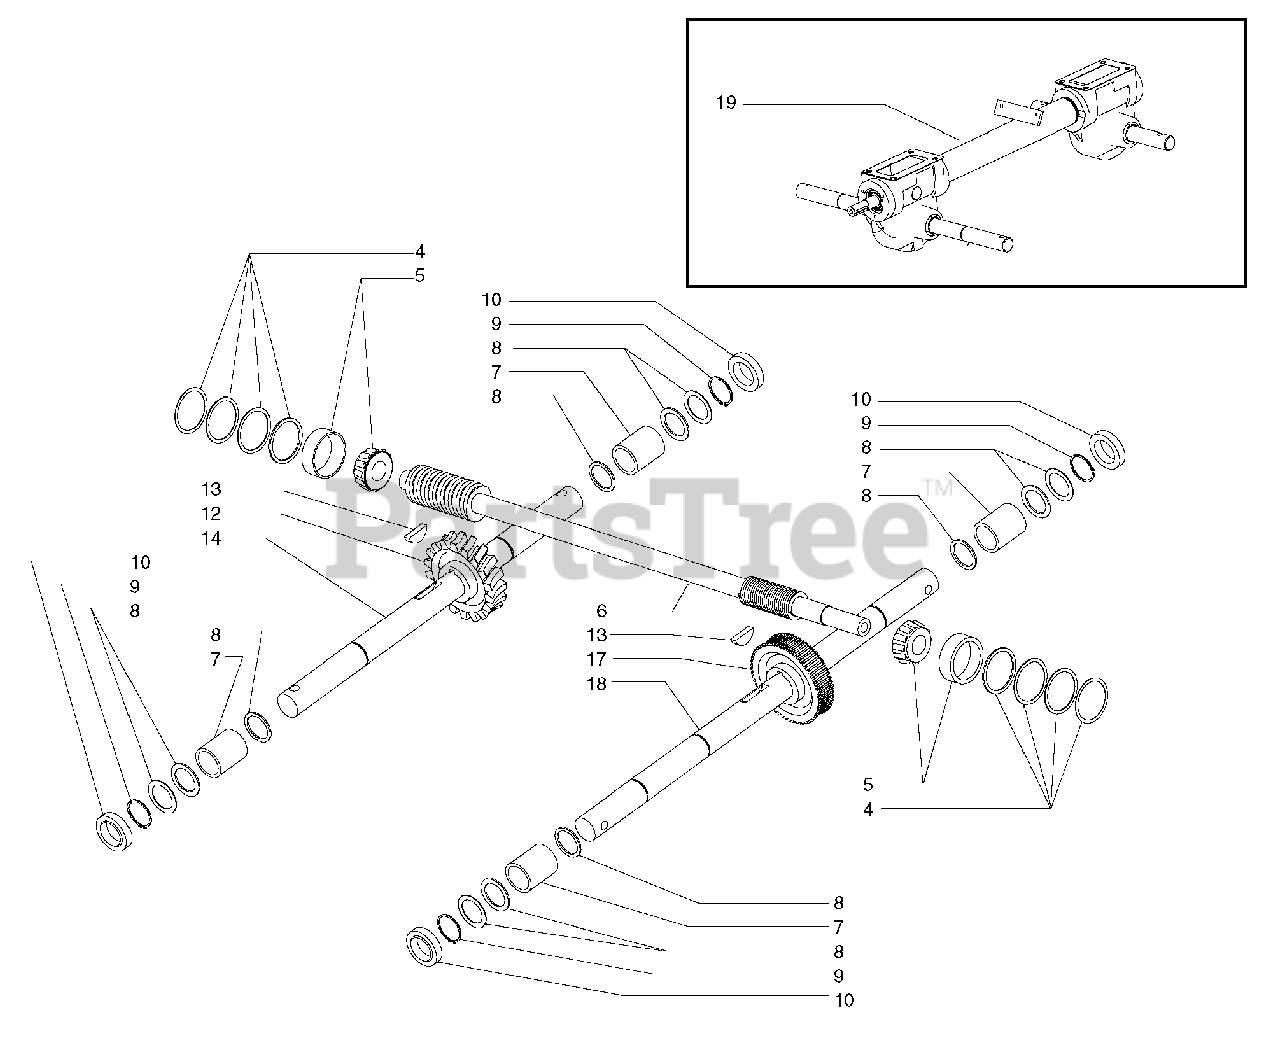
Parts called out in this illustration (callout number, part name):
4	* SHIM, Drive shaft
5	* BEARING, Tapered Roll
6	* SHAFT, Drive SRT
7	* BUSHING
8	* SPACER, 1" ID x 1-1/4 OD
9	RING, Retainer Shaft
10	SEAL, Oil, Housing
12	* GEAR, Tine
14	* SHAFT, Tine
17	* GEAR WHEEL
18	* SHAFT, WHEEL, Long
19	TRANSMISSION ASSEMBLY
